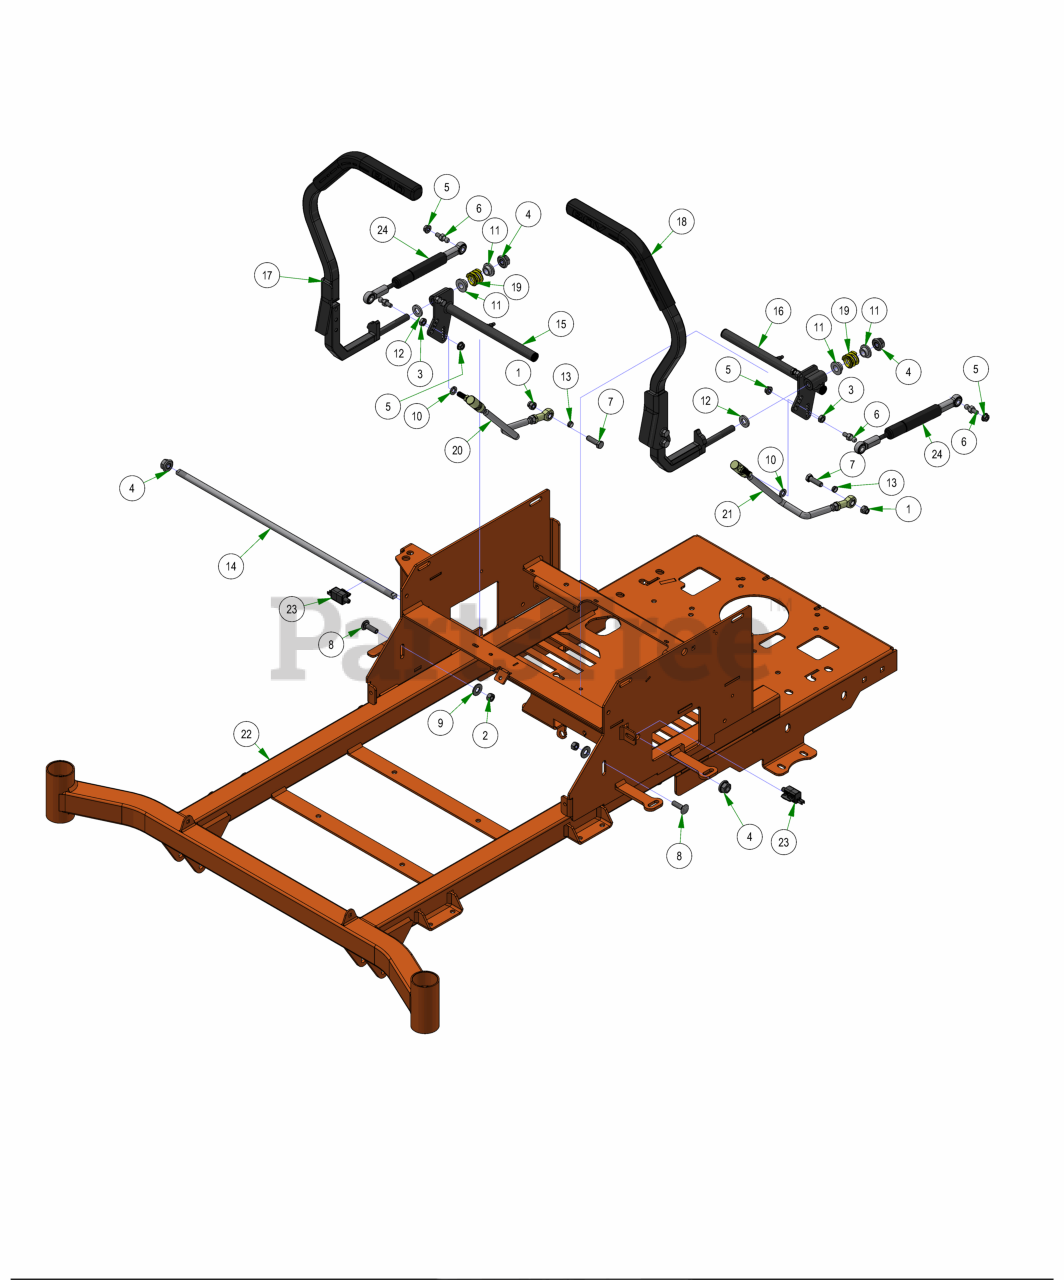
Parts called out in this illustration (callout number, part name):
1	3/8-16 NYLON INSERT LOCKNUT ZINC
2	3/8-16 HEX NUT ZINC
3	3/8-24 HEX NUT ZINC YELLOW
4	1/2-13 NYLON INSERT FLANGE LOCKNUT ZINC
5	5/16-18 HEX SERRATED FLANGE NUT HARD/ZINC
6	10mm Damper Ball Stud-Steering
7	3/8-16 X 1-1/4 HEX CAP SCREW (GR.5) ZINC
8	3/8-16 X 1-1/4 CARRIAGE BOLT ZINC
9	3/8 FLAT WASHER USS (1" OD) ZINC
10	3/8 SPLIT LOCKWASHER ZINC
11	.525 ID SHOULDER WASHER NYLON
12	.505 ID X 1.000 OD X .125 THICK FLAT WASHER NYLON
13	Drive Arm Transaxle Spacer
14	2021 Maverick Steering Actuator Rod
15	2021 Maverick Drive Arm Actuator RH Assembly
16	2021 Maverick Drive Arm Actuator LH Assembly
17	Small Mower Square Drive Arm RH Assembly
18	Small Mower Square Drive Arm LH Assembly
19	Drive Lever Spring
20	Push Rod-Right
21	Push Rod-Left
22	2025 MZ-Avenger 54-60 Frame
23	Rail Mount Safety Switch
24	ZT Avenger Steering Dampener
